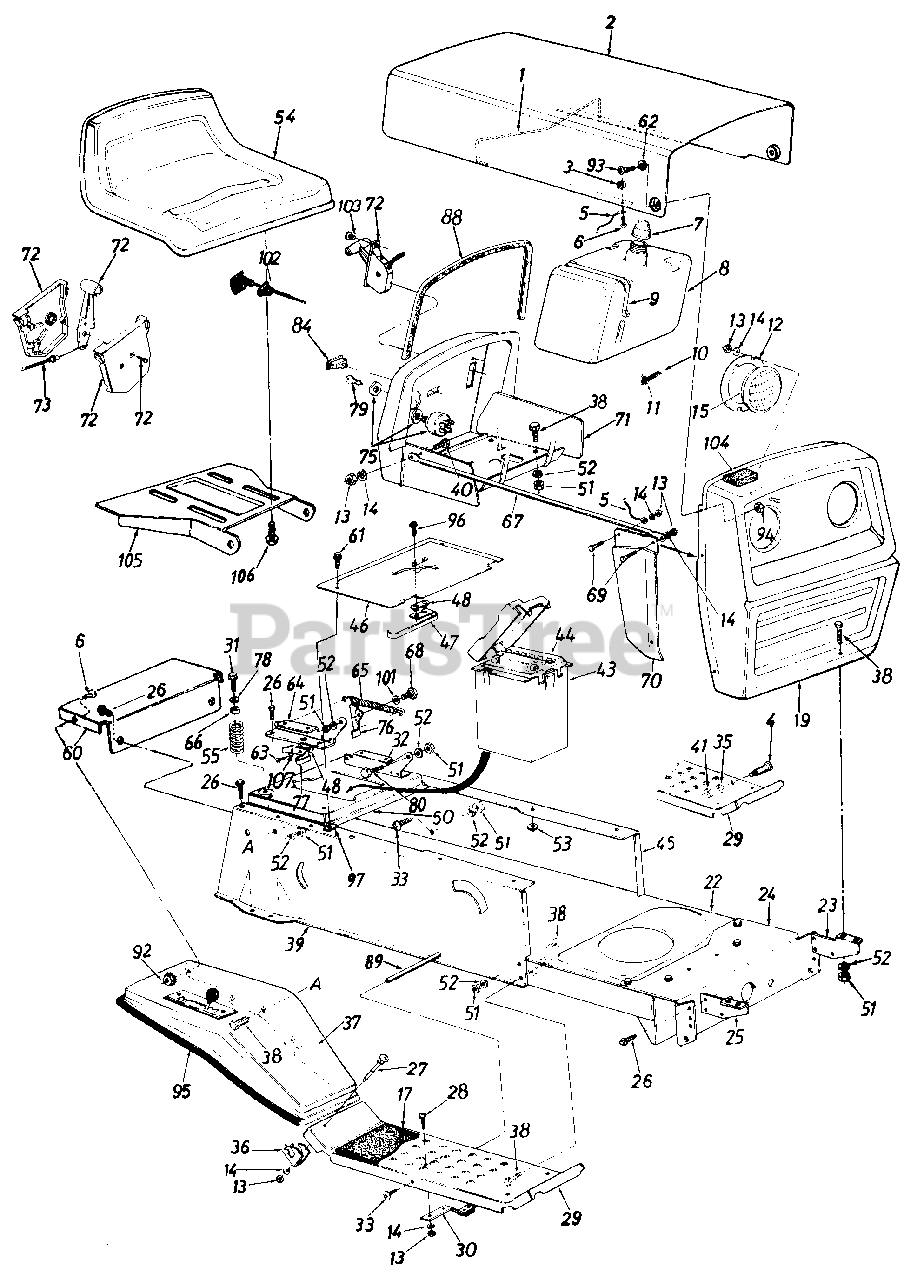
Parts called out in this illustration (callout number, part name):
1	Hood Spring
2	Hood
3	Hex Sems Nut #10-24 Thd.
4	Shld. Bolt .5" Dia. x 840"
5	Hood Stop 7" Lg.
6	Truss Hd. Scr. #10-24 x 1/2"
7	Fuel Cap Gauge
8	Fuel Tank
9	Tie Strap
10	Fuel Line
11	Hose Clamp
12	Headlight Retainer
13	Hex Nut 1/4-20 Thd.
14	L-Wash. 1/4" I.D.
15	Headlight
17	Foot Pad
23	Grille Mount Brkt.
24	Front Pivot Brkt.
25	Grille Mount Brkt.
26	Hex Wash. Hd. AB-Tap Scr. 5/16 x .75" Lg.
27	Carriage Bolt 1/4-20 x 2.0"
28	Carriage Bolt 1/4-20 x .62"
29	Running Board
30	Blade Brake Ass'y.
31	Hex Wash. Hd. Tap Scr. 5/16-18 x 1" Lg.
32	Seat Pivot Brkt. Support L.H.
33	Truss Mach. Scr. 5/16-18 x .75" Lg.
35	L-Wash. 3/8" I.D.
36	Fender Clamp
37	Fender
39	R.H. Side Frame
40	Hex Bolt 1/4-20 x .62" Lg.
41	Hex Nut 3/8-16 Thd.
43	Battery Box w/Cover
44	12-V Battery
45	L.H. Side Frame
46	Shift Cover
47	Reverse Safety Switch
48	Insulator Nut Plate
50	Hitch Plate
51	Hex Nut 5/16-18 Thd.
52	L-Wash. 5/16" I.D.
53	Ext. L-Wash. 5/16" I.D.
54	Seat Ass'y.
55	Compression Spring
62	Washer .39" I.D. x .62"
63	Hex Wash. AB-Tap Scr. #8 x .5" Lg.
64	Seat Pivot Brkt. Support R.H.
65	Ext. Spring 5.31" Lg.
66	Bushing
67	Grille Support Rod
68	Shld. Bolt .437" Dia. x .268"
69	Truss Hd. Scr. 1/4-20 x .75"
70	R.H. Grille Side Panel
73	Throttle Control Wire
75	Ignition Switch
76	Seat Lift Bracket
77	Spring Switch
78	Fl-Wash. .344" I.D.
79	Ignition Key
80	Shld. Bolt .437a Dia. x .162"
84	Light Switch
88	Molding Strip 27" Lg.
89	Running Board Rod
92	Hex Sems Nut #10-24 Thd.
93	Shld. Bolt .375" I.D. x .125
94	L-Nut 1/4-28 Thd.
95	Trim Strip 62" Lg.
96	Hex Wash. Hd. AB-Tap Scr. #8 x .50" Lg.
97	Speed Nut #10Z
101	Spr-Wash. .445" I.D. x .75" O.D.
102	Choke Control 29" Lg.
103	Truss Mach. AB-Tap Scr. #10 x .50" Lg.
104	Foam Strip 3/8" x 1-1/8" x 1-1/2 "
105	Seat Pivot Brkt.
106	Hex Hd. Tap Scr. 3/8-16 x .75" Lg.
107	Fiber Washer
